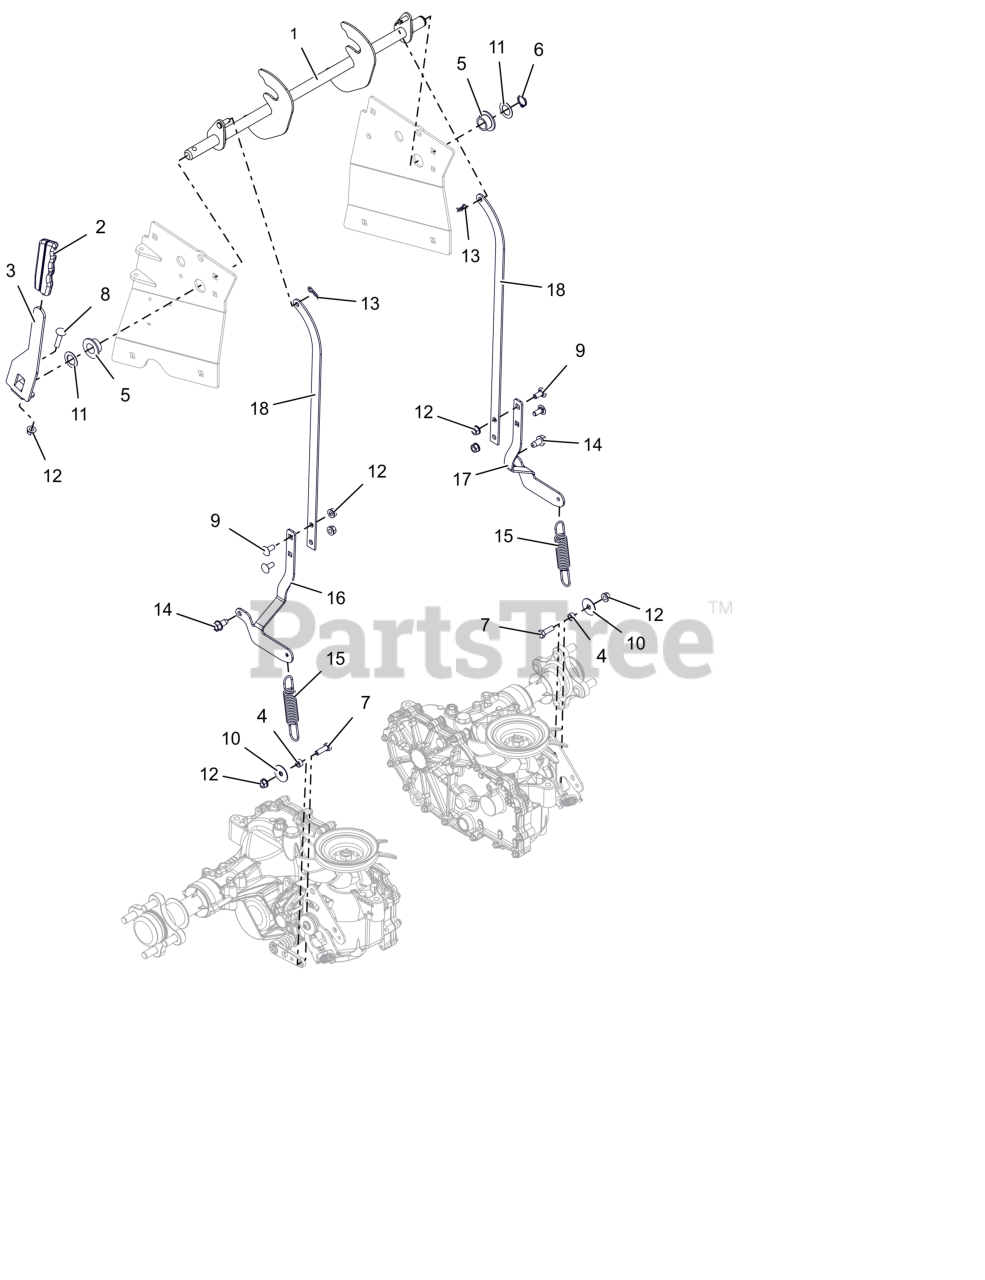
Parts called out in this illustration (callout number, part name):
1	WLDMT, 48-52" PARK BRAKE SHAFT
2	GRIP, PARKING BRAKE (GREY)
3	HANDLE, PARK BRAKE (BLACK)
4	BSHG-SLV .344 X .500 X .260
5	BSHG-FLG .762X1.0X.580X1.48 NY
6	RG-RTNG-EXT .689X.078
7	BLT,HEX .31-18X1.00 G5 ZCC
8	BLT,RHSN .31-18X1.50 G5 ZCC
9	BLT, RHSSN.31-18X.750 G5 ZCC
10	WSHR, FLT .347X1.254X.048 ZCC
11	WSHR, FLT .760X1.225X.032 ZCC
12	NUT,LK-CTR-FLG .31-18 GF ZCC
13	PIN, HAIR #213 .08X1.19 ZCC
14	SCR,TAP .375-16X.75 HWH TR ZCC
15	SG-TENS .105X.85X5.00 WLD 40
16	LINKAGE, PARK BRAKE LOWER RH (BLACK)
17	LINKAGE, PARK BRAKE LOWER LH (BLACK)
18	LINKAGE, PARKER BRAKE (BLACK)
